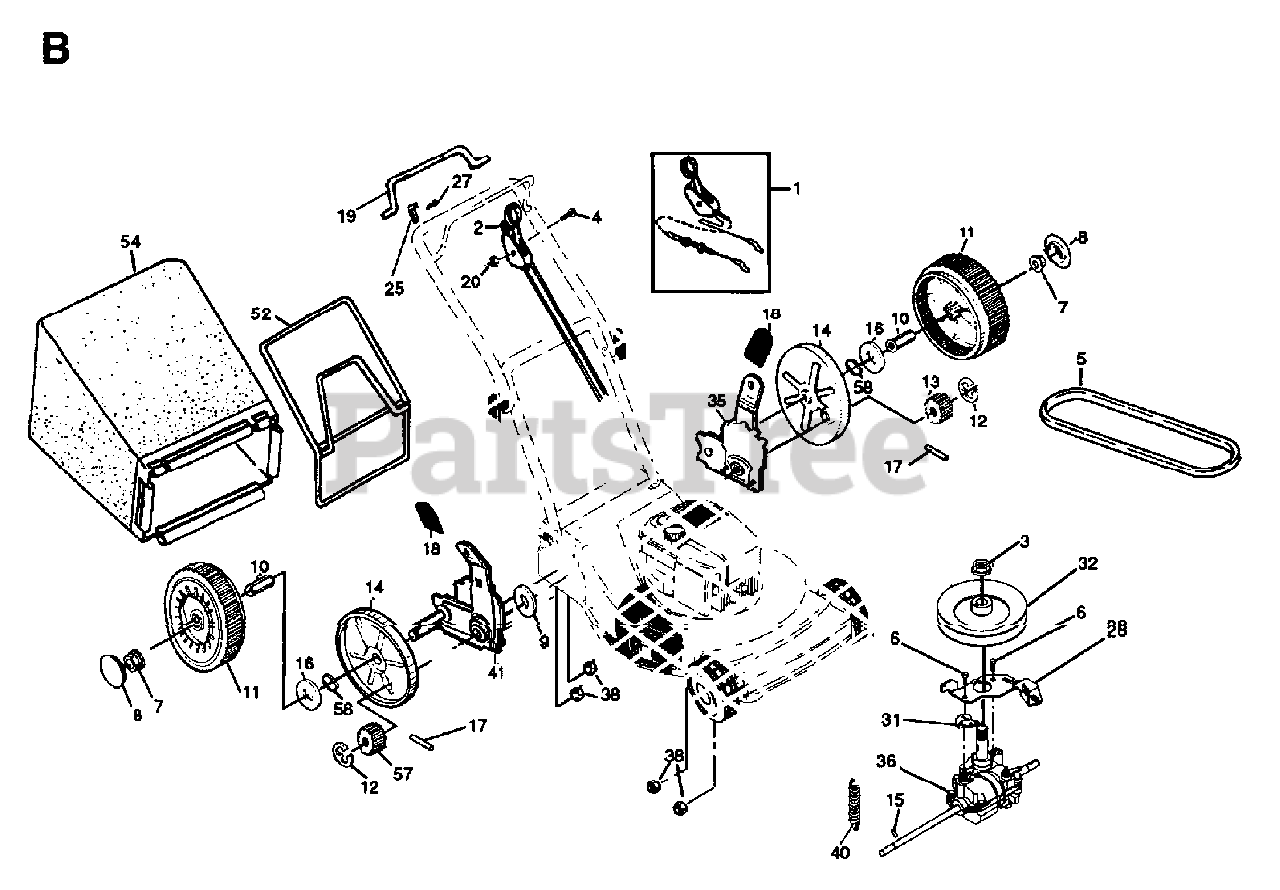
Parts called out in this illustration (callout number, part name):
2	KIT/HEAD CONTROL
3	METRIC NUT
4	SCREW 1/4-20 X 2.12
5	DRIVE BELT
7	HEX FLANGE LOCKNT
9	THRUST WASHER
10	BUSHING PM
12	E-RING 7/16 RE
14	DUST SHROUD PM
15	PIN.SPRING.THRUST
16	WASHER FLUT
17	DRIVE PAWL
18	SELECTOR KNOB
25	BRACKET UPSTOP
27	TAPPING SCREW
36	TRANSMISSION
38	NUT
58	WAVE WASHER
